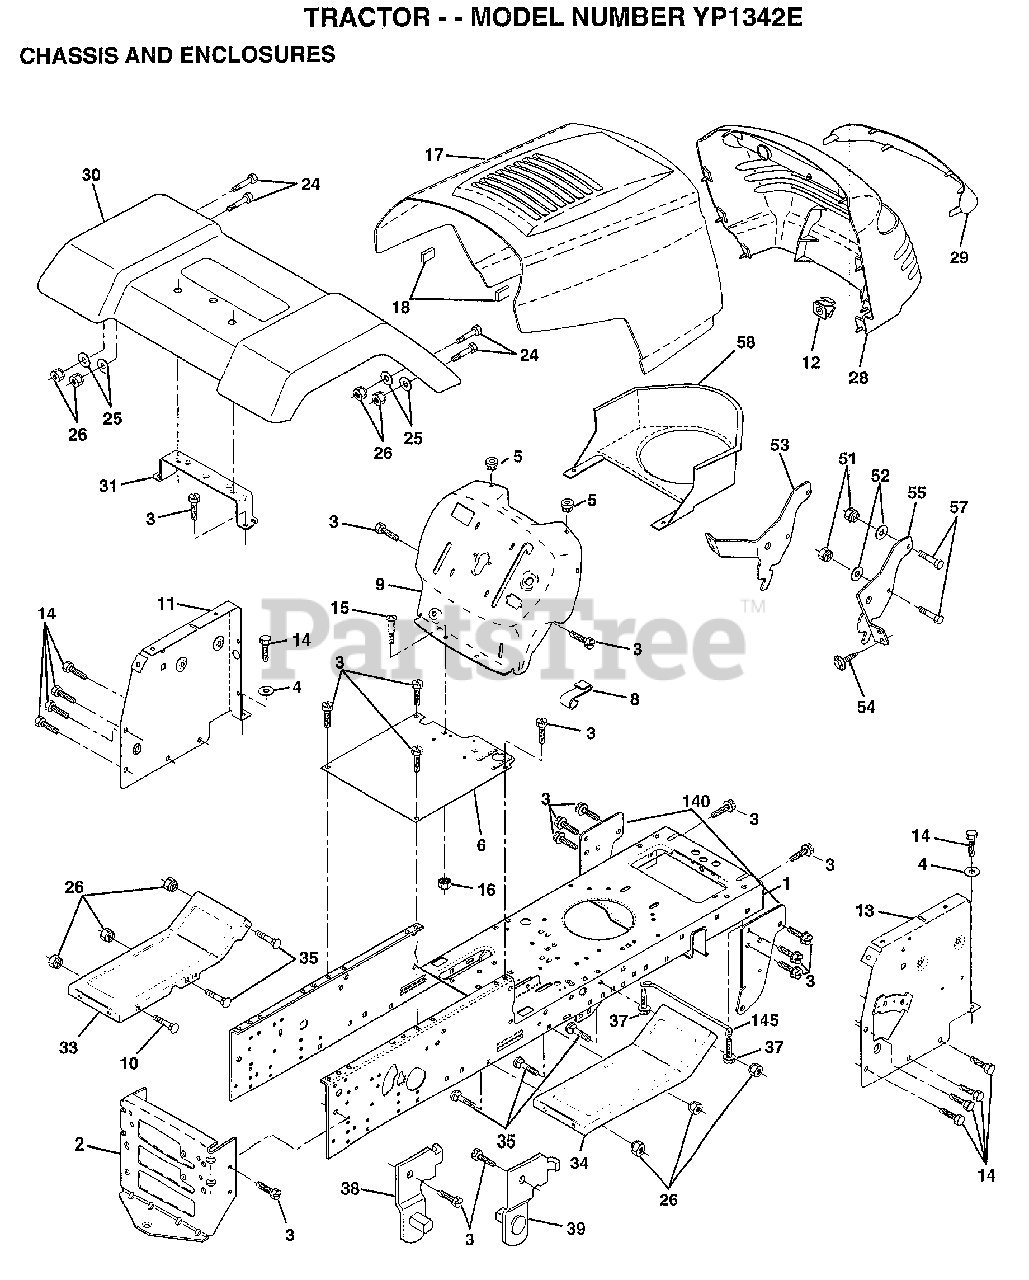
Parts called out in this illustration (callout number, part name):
1	CHASSIS.STAMPING
3	SCREW
4	WASHER
5	BUMPER-HOOD/DASH
6	SADDLE
8	CLIP.RETAINER
9	DASH.SILKSCREEN
11	"PANEL-DASH,LH"
12	CLIP.TINNERMAN
13	"PANEL-DASH,RH"
14	SCREW LT
15	SCREW
17	"HOOD W/TRIM,MS428"
24	BOLT
25	WASHER
26	NUT
28	GRILL
29	GRILLE.LENS
30	FENDER ASM.
31	BRKT FENDER
33	FOOTREST PNT LH
34	FOOTREST.RH.LT/GT
35	BOLT
37	SCREW LT
38	BRACKET ASM LH
39	BRACKET ASM RH
51	NUT
52	WASHER
53	BRACKET.GRILLE.LH
54	SCREW.HEX.WS.HD
55	BRACKET.GRILLE.RH
58	AIR DUCT
140	BRKT SUSPENSION
145	"ROD POVOT,CHASSIS"
